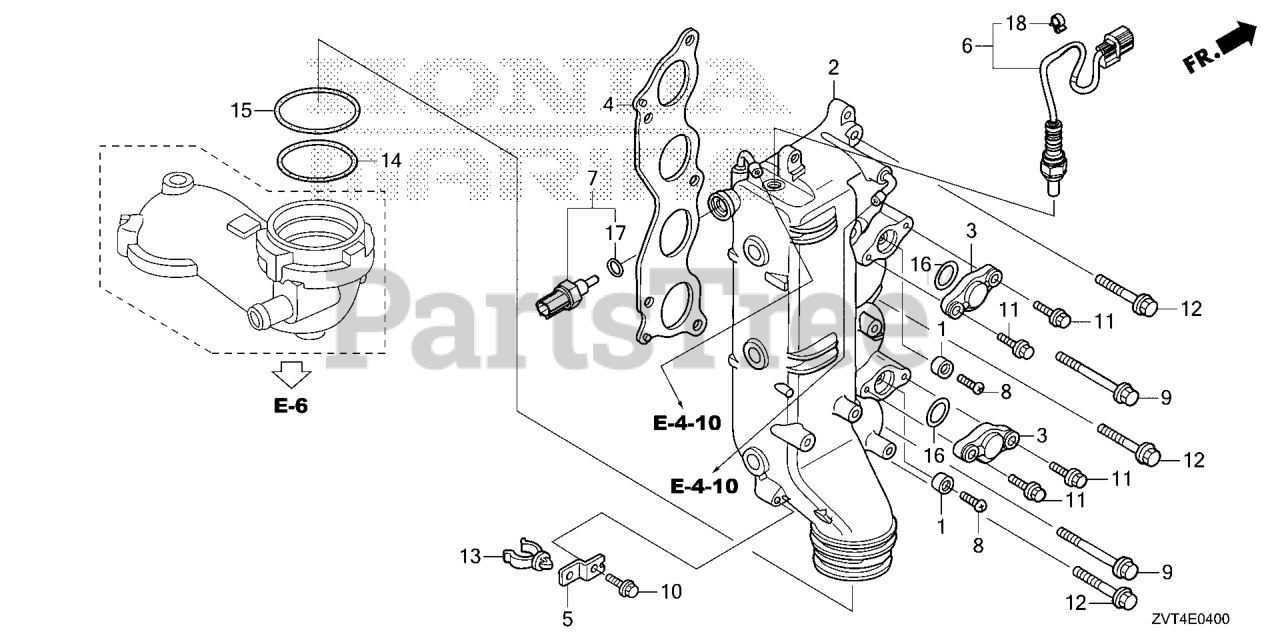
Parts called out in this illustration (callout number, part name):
1	METAL, ANODE
2	MANIFOLD COMP *NH8*
3	COVER, EX. MANIFOLD *NH8* (DARK GRAY)
4	GASKET, EX. MANIFOLD
6	SENSOR, OXYGEN
7	SENSOR ASSY., WATER TEMPERATURE
8	BOLT, FLANGE (6X18)
9	BOLT, FLANGE (10X75)
10	BOLT, FLANGE (6X14)
11	BOLT, FLANGE (6X22)
12	BOLT, FLANGE (10X45)
13	CLAMP B, WATER TUBE
14	O-RING (76.4X3.1)
15	O-RING (79.8X3.1)
16	O-RING (37X2.4)
17	O-RING (9.5X1.9)
18	CLIP, HARNESS BAND (145MM) (BLACK)
